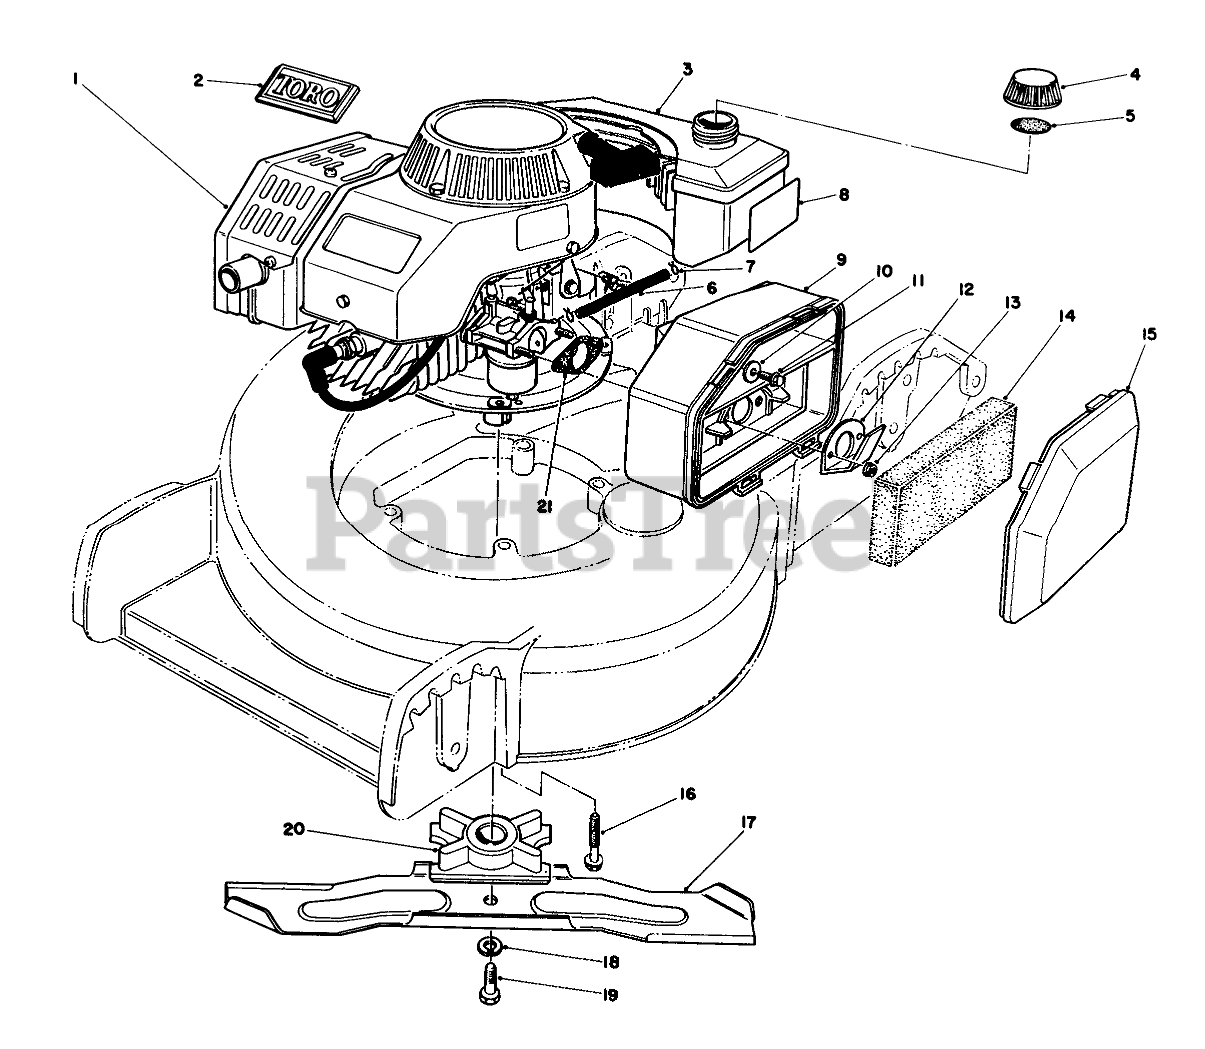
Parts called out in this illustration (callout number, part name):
1	Engine
2	TORO LOGO PLT
3	Gas Tank Assembly
4	Gas Cap Assembly (Incl. Ref. #5)
5	GAS CAP GASKET
6	FUEL LINE
7	CLAMP-HOSE
8	Decal-Maintenance
9	AIR CLEANER
10	WASHER-FLAT
11	SCREW-HH
12	SPIT BACK DEFLECTOR
13	NUT-LOCK
14	FILTER
15	AIR CLEANER COVER
16	SCREW-HHF
17	Blade
18	WASHER-LOCK
19	SCREW-HH
20	BLADE RETAINER
21	GASKET-AIR CLEANER
